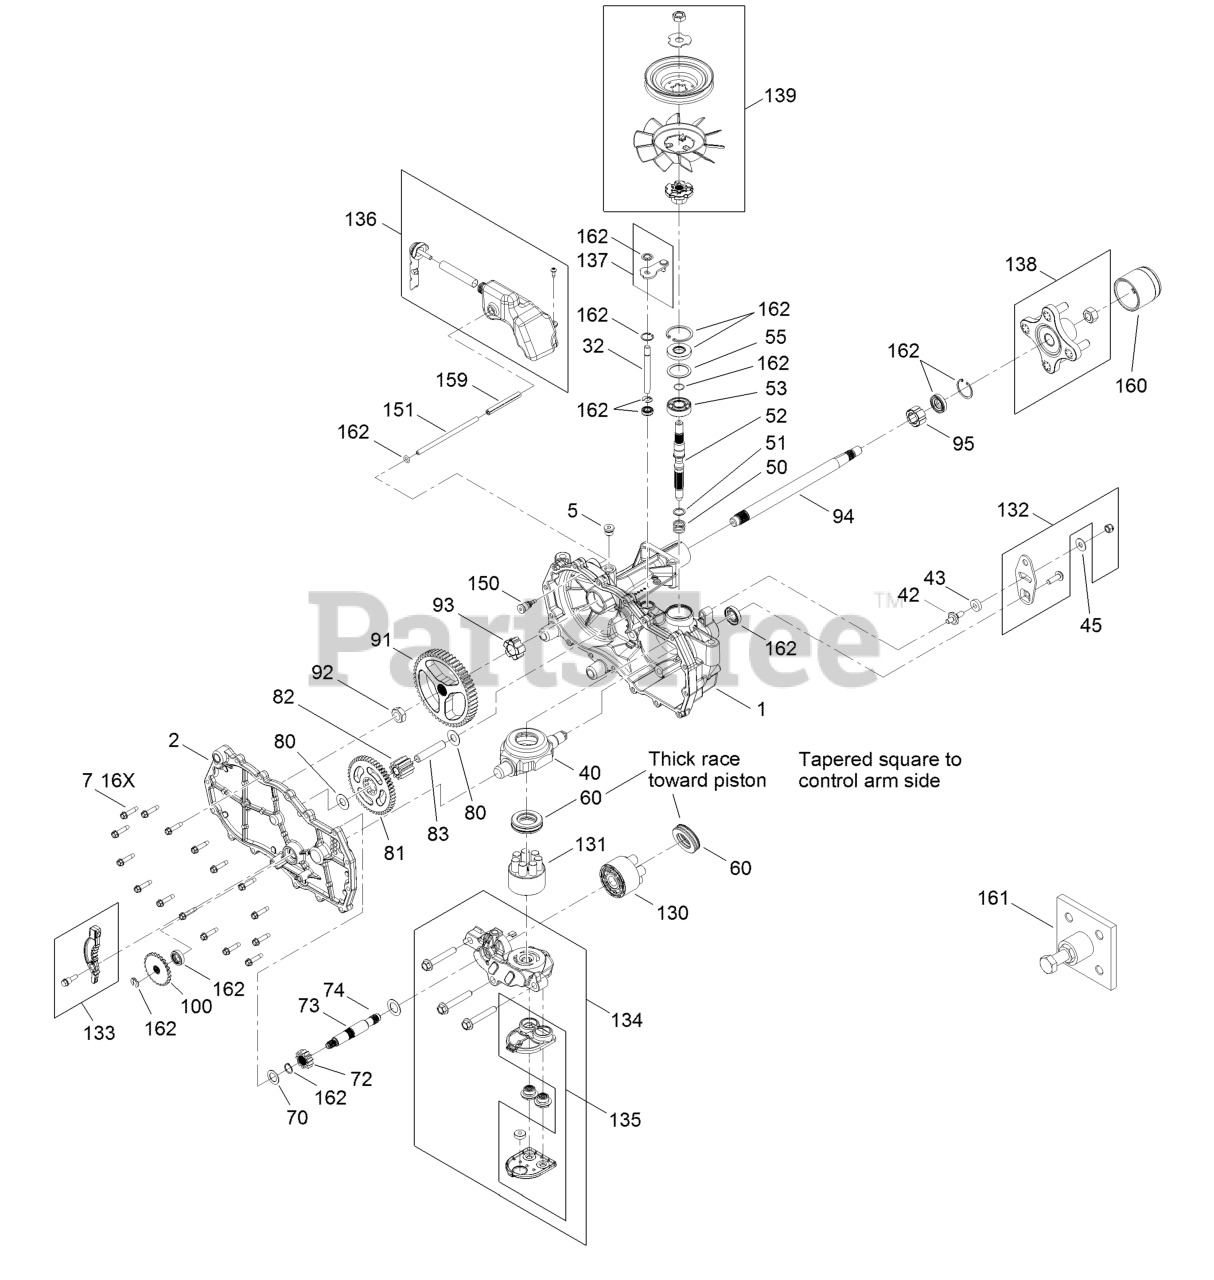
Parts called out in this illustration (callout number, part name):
1	Main Housing ASM
2	Housing Side Kit
5	Plug-Thread, Straight
7	Screw-HHF
13	Sealant
32	Rod-Bypass
40	Swashplate-Trunnion
43	Puck-Friction
50	Spring-Compression
52	Shaft-Input
53	Bearing-Ball
60	Bearing-Thrust
70	Washer-Flat
72	Gear-Pinnion, 13T
73	Shaft-Motor
80	Washer
81	Gear-10T/48T
82	Gear-Jackshaft, 10T
83	Pin-Jackshaft
91	Gear-Bull
93	Bushing-Inboard
94	Shaft-Axle
95	Bearing-Sleeve
100	Disc-Brake, Cog
130	Cylinder Block Kit
131	Pump Block ASM
132	Control Arm Kit
133	Brake Arm Kit
134	Center Section Filter Kit
135	Filter Kit
136	LH Expansion Tank Kit
137	Bypass Arm Kit
138	Hub Kit
139	Fan Pulley Kit
150	Fitting-SAE
159	Case-Tube
160	Cap-Axle
161	Puller-Hub, 4 Bolt
162	Seal And Ring Kit
